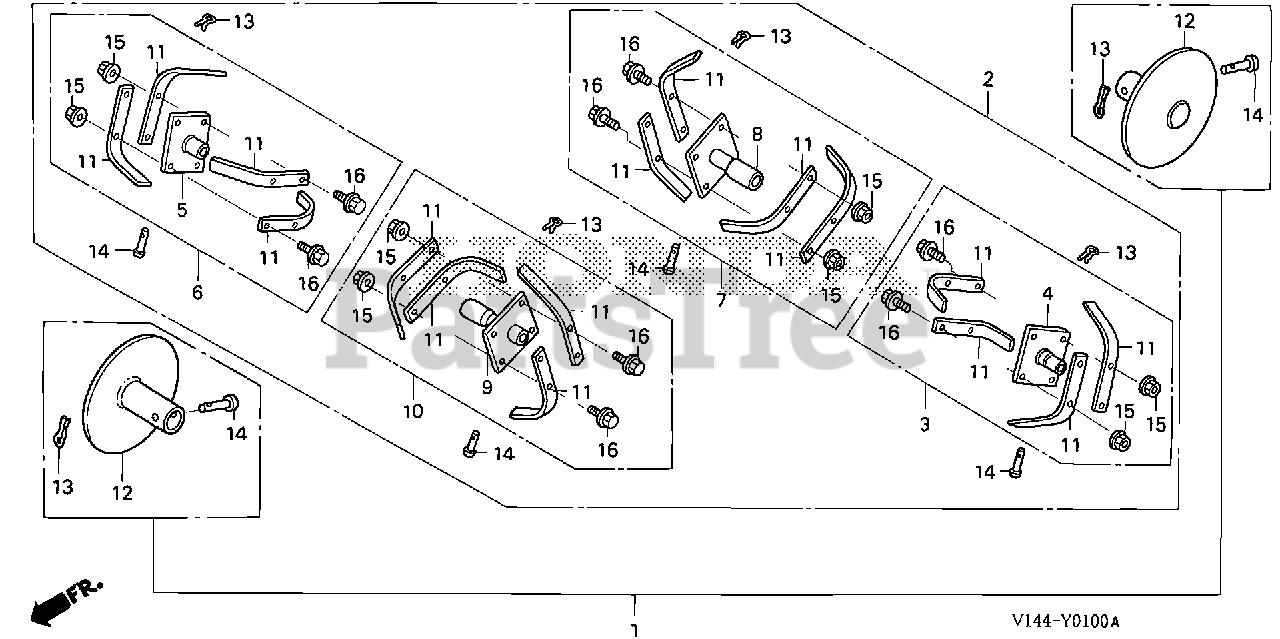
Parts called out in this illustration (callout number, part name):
1	DISK KIT, SIDE
2	ROTOR KIT *NH1* (BLACK)
3	PIPE, L. MAIN *NH1* (BLACK)
4	PIPE, L. ROTOR MAIN
5	PIPE, R. ROTOR MAIN
6	PIPE, R. MAIN *NH1* (BLACK)
7	PIPE, L. EXTENSION *NH1* (BLACK)
8	PIPE, L. ROTOR EXTENSION
9	PIPE, R. ROTOR EXTENSION
10	PIPE, R. EXTENSION *NH1* (BLACK)
11	TINE A, ROTOR
12	DISK, SIDE
13	PIN, SNAP (7MM)
14	PIN, WHEEL (8X35)
15	NUT, FLANGE (8MM)
16	BOLT, FLANGE (8X18)
